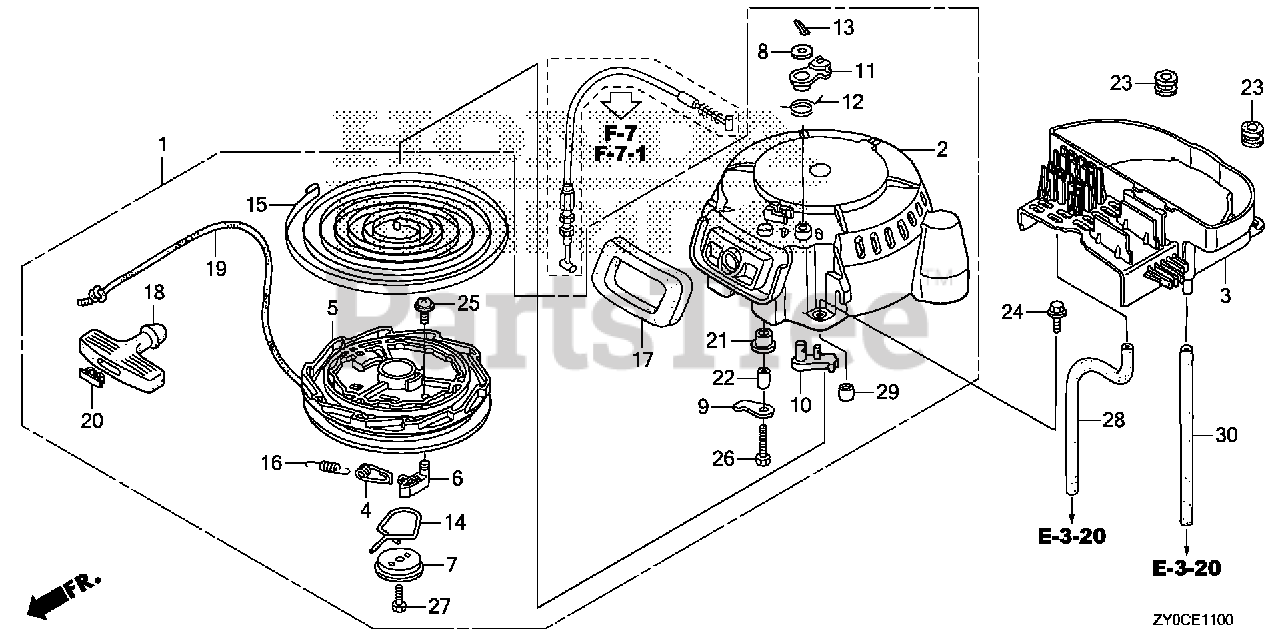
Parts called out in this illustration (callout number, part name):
1	STARTER ASSY., RECOIL
2	CASE, RECOIL STARTER
3	CASE B, STARTER
4	GUIDE, RECOIL STARTER
5	REEL, RECOIL STARTER
6	RATCHET, STARTER
7	PLATE, FRICTION
9	WASHER, THRUST
10	STOPPER, REEL
11	ARM, STOPPER
12	SPRING, STOPPER
13	PIN, SPLIT
14	SPRING, FRICTION
15	SPRING, RECOIL STARTER
16	SPRING, RETURN
17	SEAL, RECOIL
18	GRIP, STARTER
19	ROPE, RECOIL STARTER (N/A: USE P/N 08550-ZG921-11)
20	CAP, STARTER KNOB
21	ROLLER, STARTER
22	GUIDE, ROLLER
23	GROMMET, ENGINE COVER
24	BOLT, FLANGE (6X22)
26	BOLT, HEX. (6X25)
27	BOLT, HEX. (6X14)
28	TUBE, WATER DRAIN
29	COLLAR (6.5X11X10)
30	BULK HOSE, VACUUM (8X1000) (8X240)
